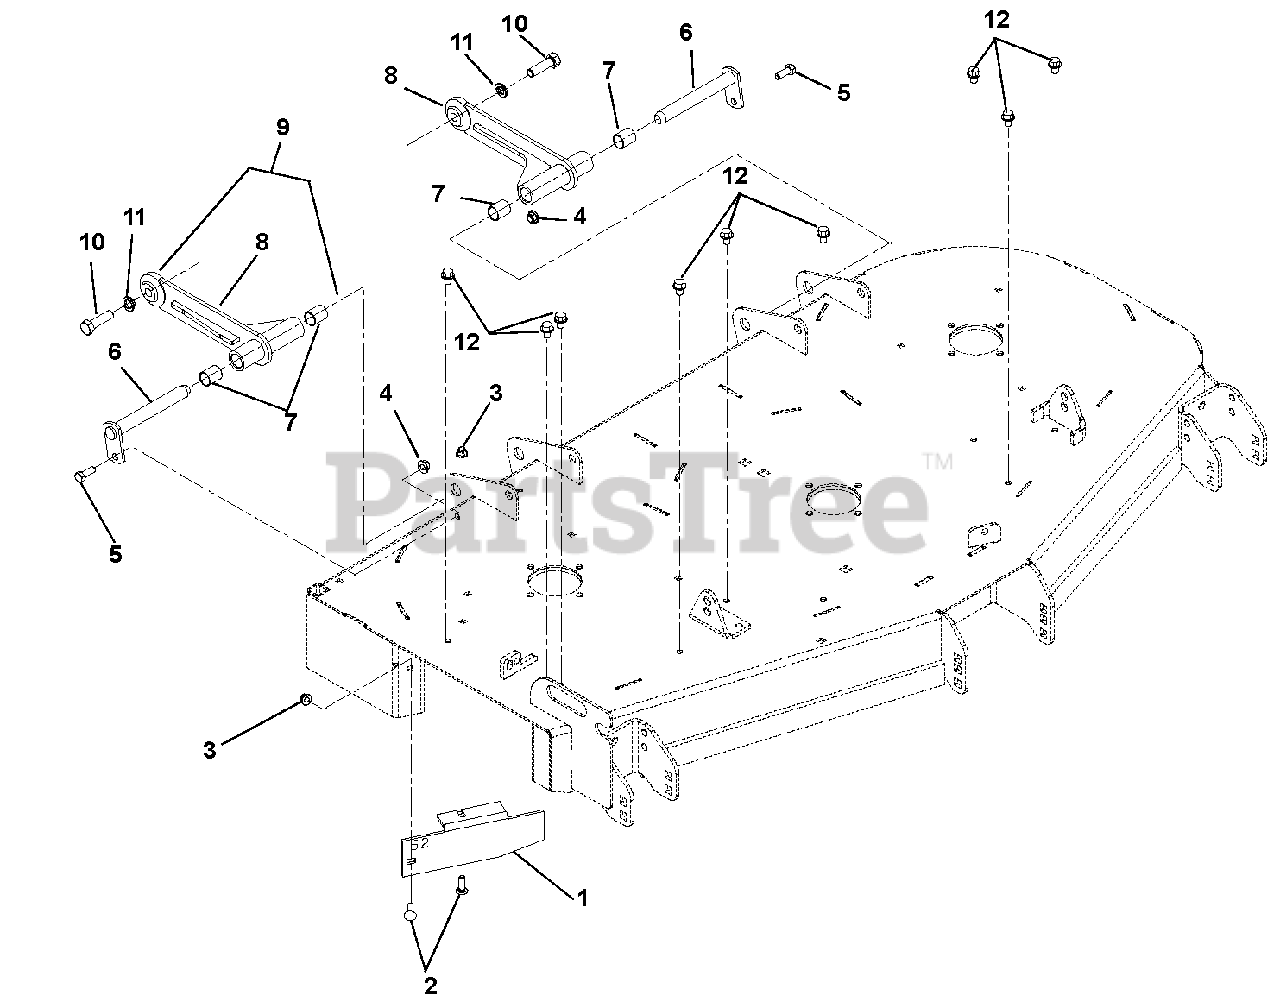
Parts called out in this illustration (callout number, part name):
1	Discharge Baffle, 44" & 48" (991082, 090)
1	Discharge Baffle, 60" (991084)
1	Discharge Baffle, 52" (991083)
2	Bolt, Round Head Square Neck .31-18 x 1.00 Grade 5
3	Nut, .31-18 Nyloc Flange
4	Nut, .38-16 Nyloc Flange
5	Bolt, Hex .38-16 x 1.00 Grade 5
6	Weldment, Mower Mounting Pin
7	Bearing, .75 x .875 x 1.00
8	Deck Pusher Arm Weldment
9	Assembly, Mower Mount Arm (Contains items 7 and 8)
10	Bolt, Hex .50-13 x 1.75 Grade 5
11	Washer, Locking .50 x .125 Regular
12	Screw, Tapping .38-16 x .50 Hex Washer Head
